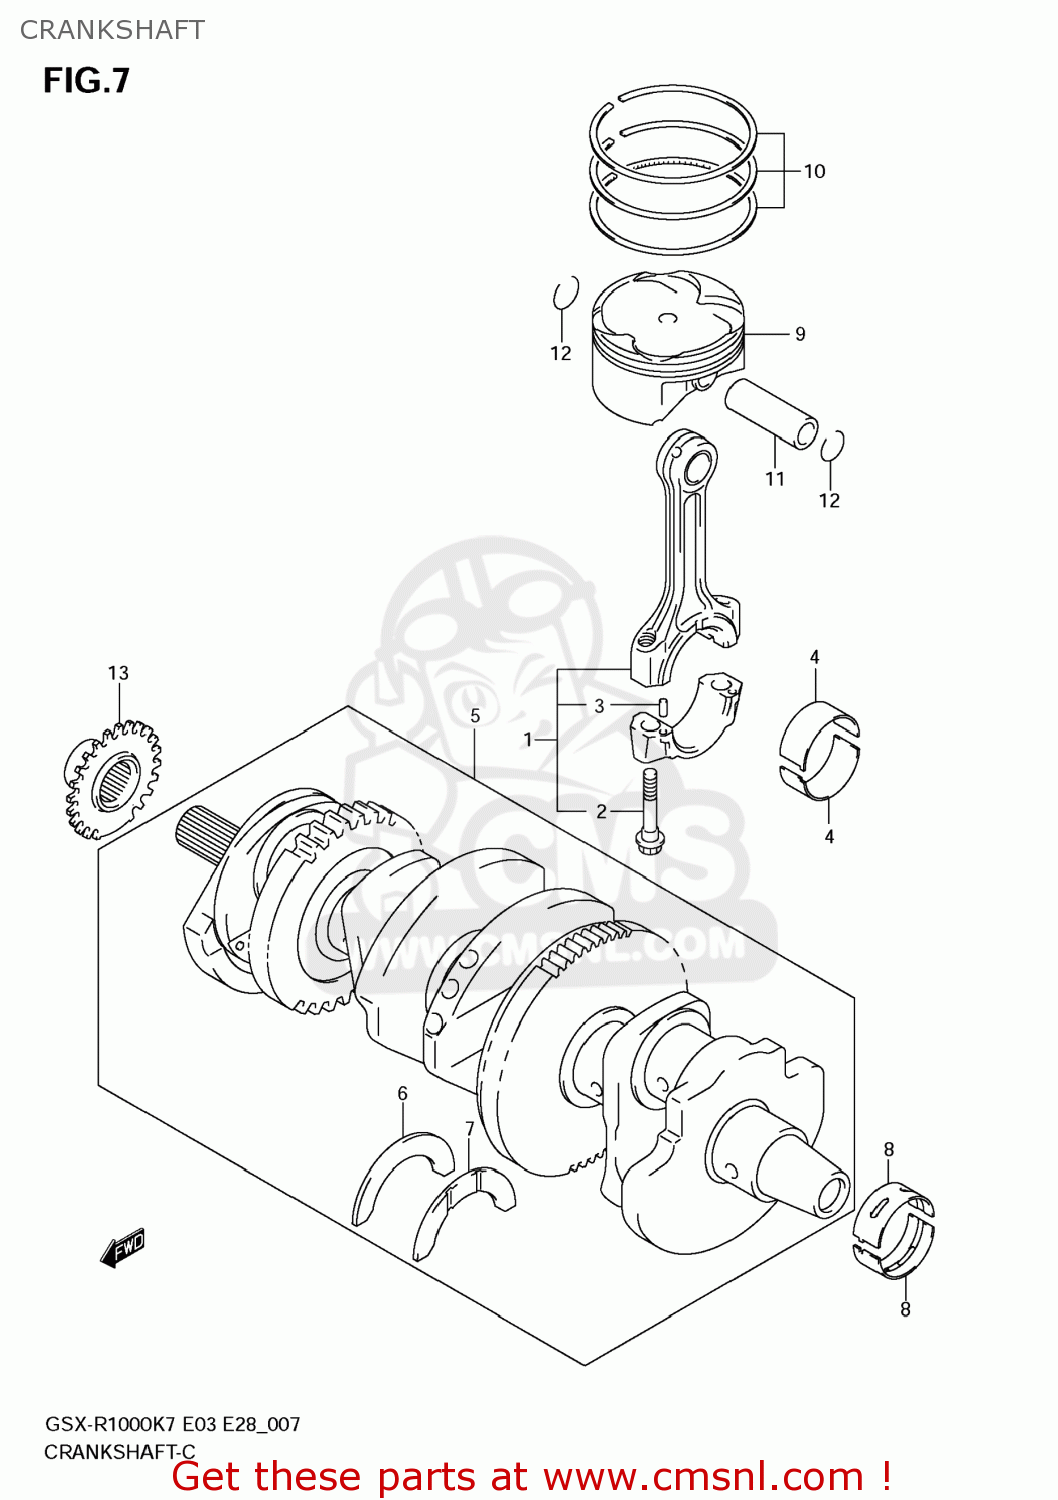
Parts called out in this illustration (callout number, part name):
1	CONNECTING ROD ASSY
2	BOLT,CONNECTING ROD
3	PIN,CONNECTING ROD
4	BEARING,CRANK PIN
5	CRANKSHAFT SET
6	BEARING,CRANK THRUST(GREEN)
7	BEARING,CRANK THRUST(RED)
8	BEARING,CRANKSHAFT
9	PISTON
10	RING SET,PISTON
11	PIN,PISTON
12	CIRCLIP
13	SPROCKET,CAM CHAIN DRIVE
